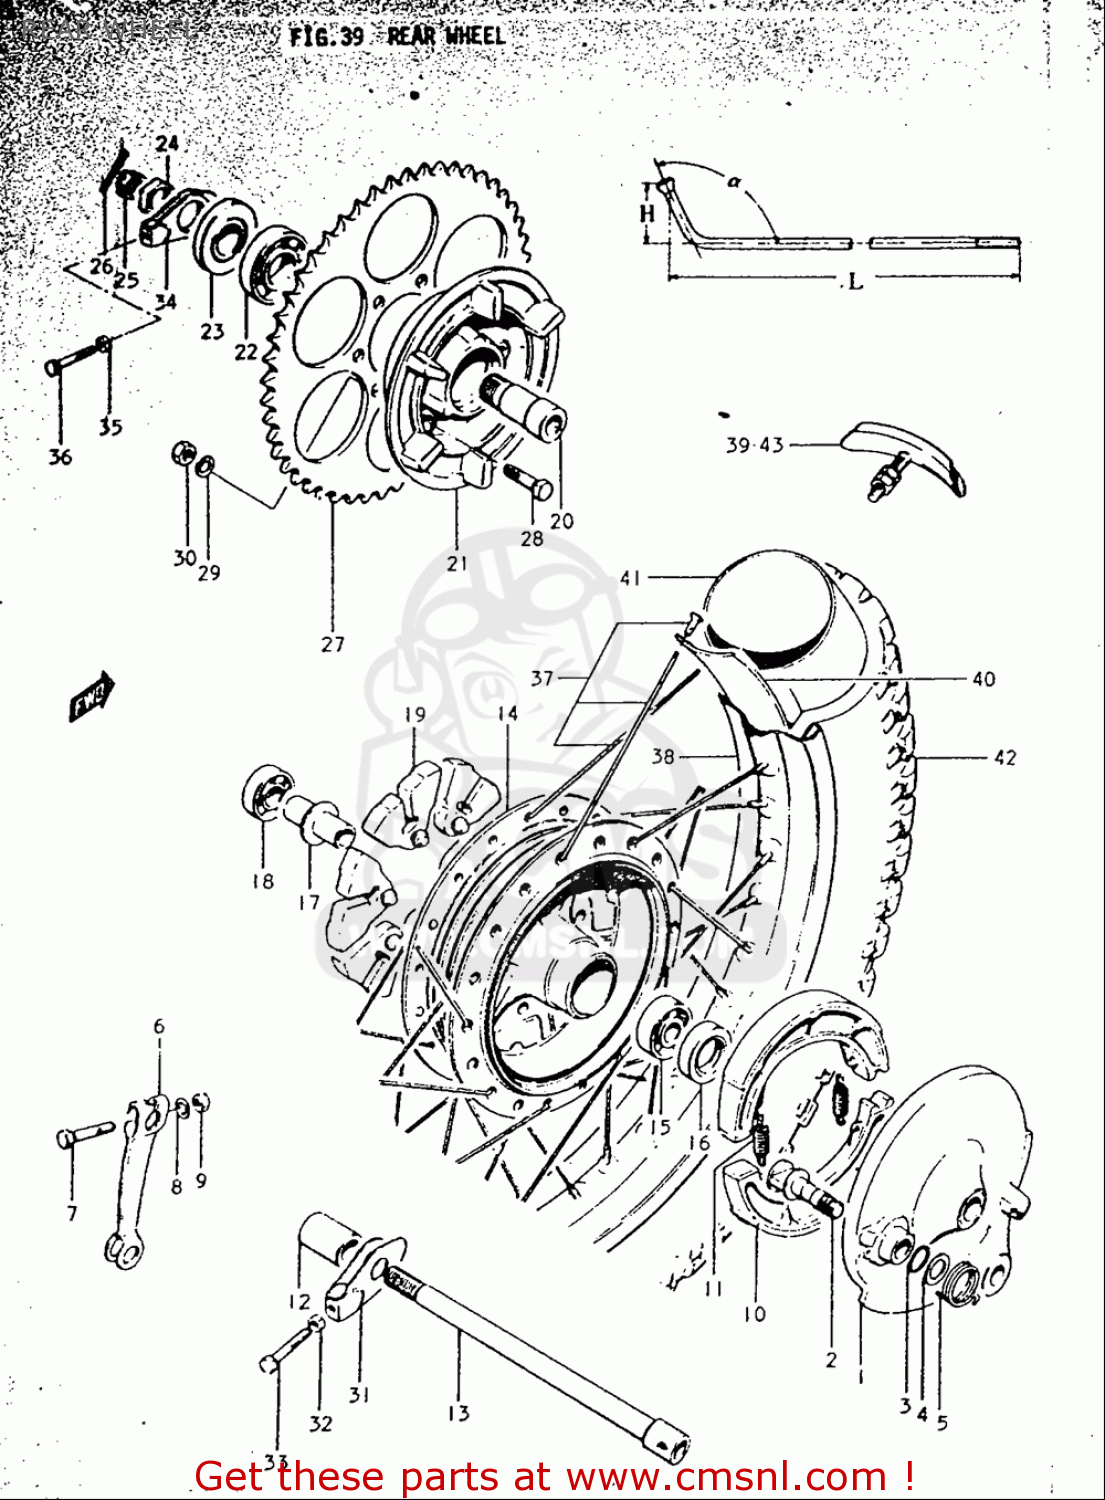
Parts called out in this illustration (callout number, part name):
3	O RING(D:2.4,ID:14.8)
4	WASHER(15.5X24X1.6)
5	SPRING
8	WASHER
9	NUT
13	AXLE,REAR
15	BEARING(17X40X12)
16	SEAL,OIL(25X40X6)
18	BEARING(17X40X12)
24	NUT
28	BOLT(10X35.5)
29	WASHER,LOCK
30	NUT
32	NUT
33	BOLT(8X50)
34	ADJUSTER,CHAIN,L
35	NUT
36	BOLT(8X50)
40	PROTECTOR,INNER TUBE
41	TUBE,INNER
